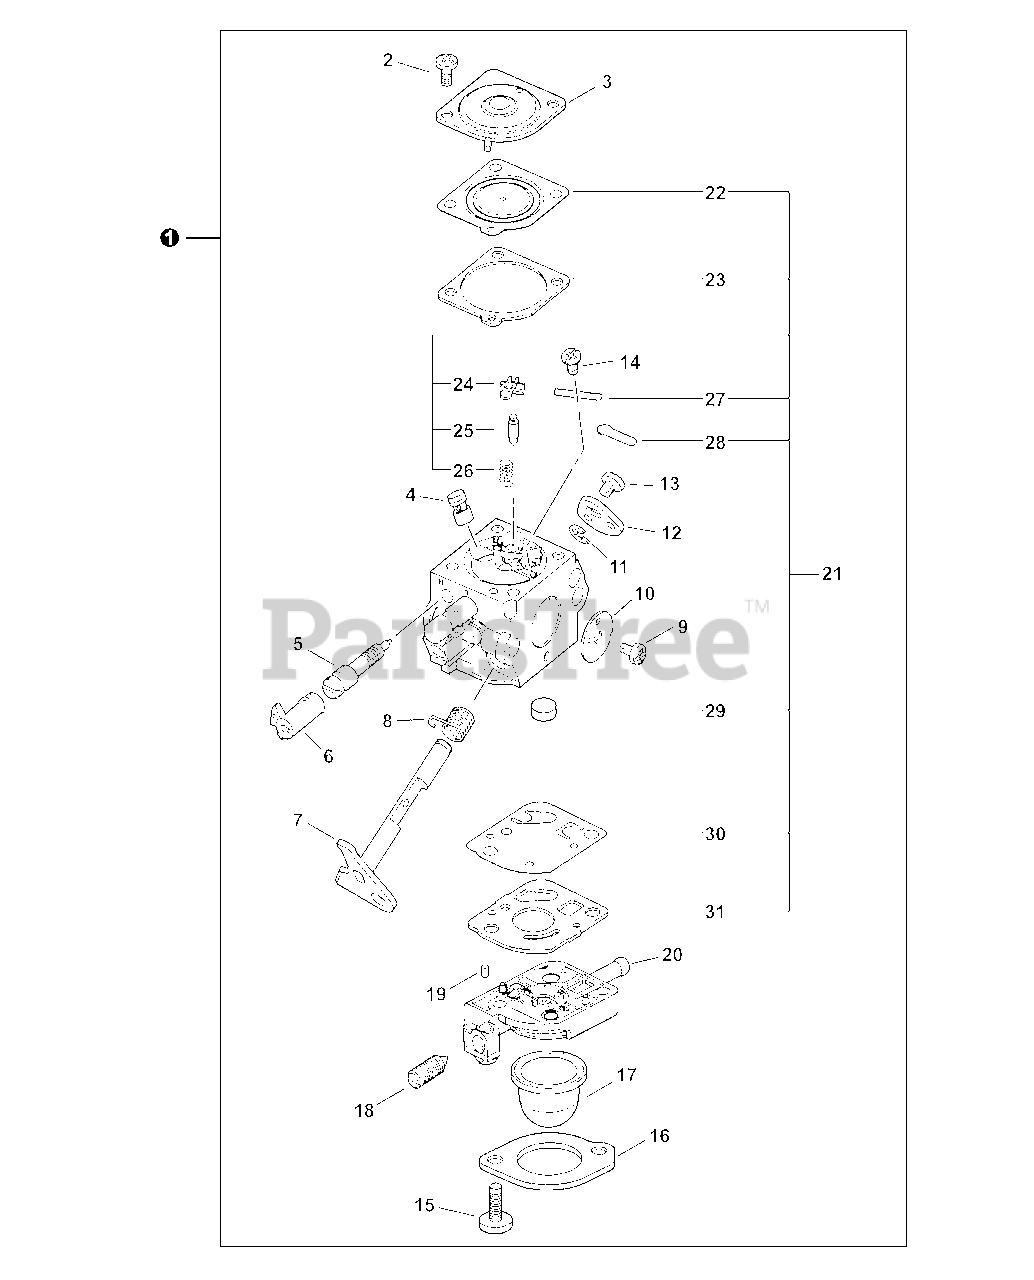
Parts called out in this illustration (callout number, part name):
1	CARBURETOR - C1U-K78
3	COVER, METERING DIAPHRAGM
4	NOZZLE, CHECK VALVE
5	NEEDLE, HIGH SPEED
6	CAP, LIMITER
7	SHAFT, THROTTLE
8	SPRING, THROTTLE RETURN
10	VALVE, THROTTLE
12	LEVER, THROTTLE
16	RETAINER
17	BULB, PURGE
19	PIECE, FRICTION
20	BODY ASSY, PURGE
21	REPAIR KIT, CARBURETOR
22	DIAPHRAGM, METERING
23	GASKET, METERING DIAPHRAGM
24	LEVER, METERING
25	VALVE, INLET NEEDLE
26	SPRING, METERING LEVER
27	PIN, METERING LEVER
28	PLUG, WELCH
29	SCREEN, FUEL INLET
30	DIAPHRAGM, PUMP
31	GASKET, PUMP
